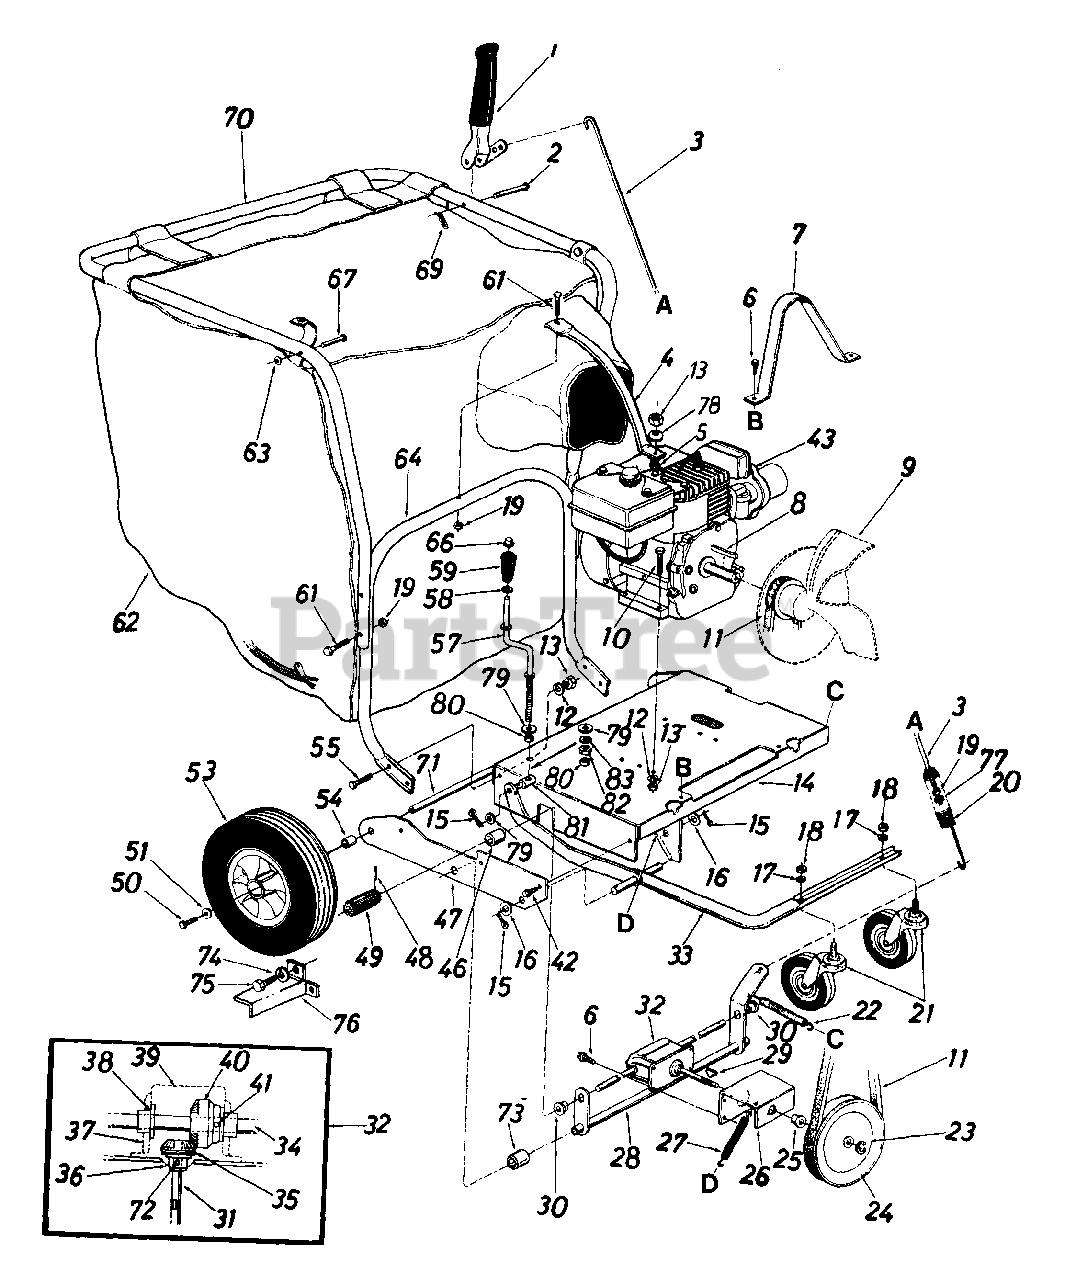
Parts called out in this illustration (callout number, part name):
3	Clutch Rod 32" Lg.
4	Handle Brace
5	Part of Engine
6	Hex Wash. Hd. AB-Tap Scr. 1/4" x .62" Lg.
11	"V" - Belt
12	L-Wash. 5/16" I.D.
13	Hex Nut 5/16-18 Thd.
16	Fl-Wash. .63" I.D. x 1.25" O.D.
17	L-Wash. 1/2" I.D.
18	Hex Nut 1/2-13 Thd.
19	Hex Cent. L-Nut 1/4-20 Thd.
20	Extension Spring .78" O.D. x .75" Lg.
21	Swivel Caster Wheel 5" Dia. x 1.25"
22	Extension Spring .38" O.D. x 7.50" Lg.
23	Snap "E" - Ring .50" Dia. Shaft
24	"V" - Pulley 5/8" x 6.50" O.D.
25	Flange Bearing .502" I.D.
28	Clutch Bracket Ass'y.
29	#2 Woodruff Key 3/32" Dia. x .81" Lg.
30	Hex Flange Bearing Bronze .625" I.D.
31	Pinion Shaft .50" Dia. x 5"
32	Gear Box Ass'y. Comp.
35	Bevel Gear .50" I.D. x 14 Teeth
36	Flange Bearing .503" I.D.
37	Gear Box
38	Flange Bearing .630" I.D.
39	Gear Box Cover
40	Bevel Gear .62" I.D. x 28 Teeth
41	Spring Pin Spiral 3/16" Dia. x 1.25" Lg.
42	Hex Wash. Hd. AB-Tap Scr. 5/16" x .75" Lg.
43	Engine
46	Spacer .63" I.D. x .88" 0 D. x .56" Lg.
49	Drive Pinion
50	Hex Locking Bolt 5/16-24 x .62" Lg.
51	Fl-Wash. .34" I.D. x .87" O.D.
53	Wheel Ass'y. Comp. 12" x 3"
54	Spacer .63" I.D. x 1.0" O.D. x .94" Lg.
55	Hex Bolt 5/16-18 x .75" Lg.
57	Height Adjustment Crank
58	Fl-Wash. .385" I.D. x .62" O.D.
59	Crank Knob
61	Hex Bolt 1/4-20 x 1.75" Lg.
62	Vacuum Bag - Felt
63	Push Speed Nut .25" Dia. Stud
67	Stud Pin .250" Dia. x 1.75"
69	Internal Cotter Pin 3/8" Dia.
70	Upper Handle
72	Spring Roll Pin 5/32" Dia. x 1.12
73	Spacer .82" I.D. x 1.0" O.D. x .305 Lg.
74	L-Wash. .265" I.D.
75	Hex Self-Tap Scr. 1/4" x 3/8" Lg.
78	Belleville Washer
79	Fl-Wash. .35" I.D. x .87" O.D.
80	Spacer .38" I.D. x .50" O.D. x .18" Lg.
81	Ferrule 3/8-8 x .38" Dia.
82	Hex Nut 3/8-8 Thd.
83	L-Wash. 3/8" I.D.
